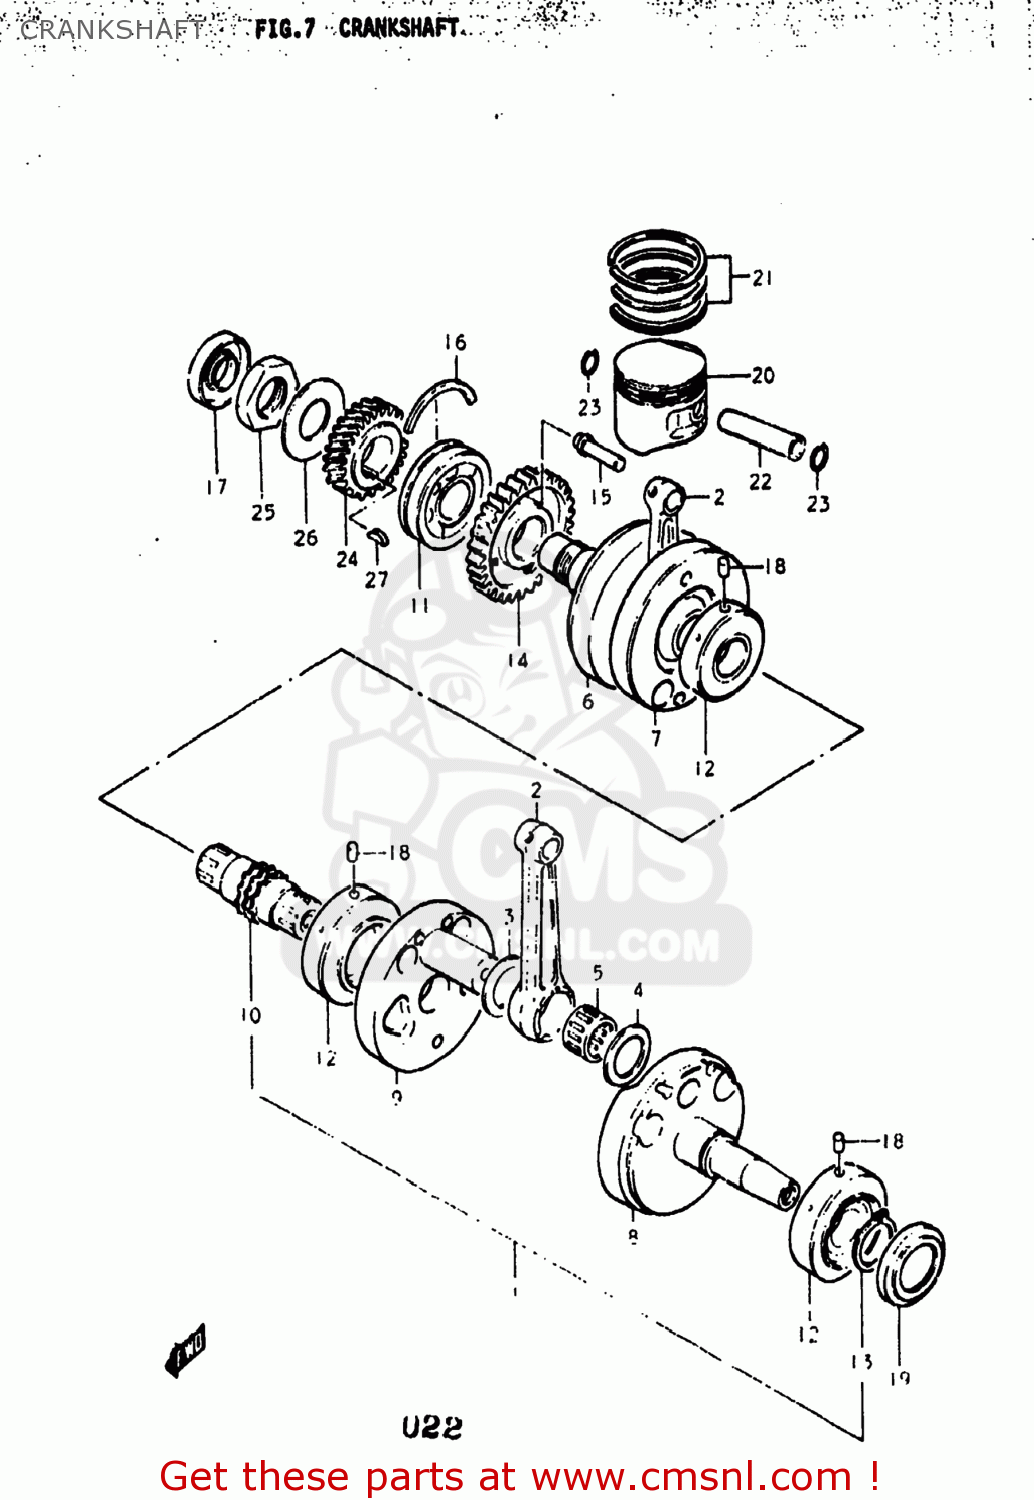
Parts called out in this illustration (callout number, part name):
1	CRANKSHAFT ASSEMBLY
2	CONNECTING ROD
3	WASHER (28X48X2)
4	WASHER(28X48X1)
5	BEARING(28X38X19.8)
6	CRANKSHAFT
7	WEB,CRANK
8	CRANKSHAFT,LEFT
9	WEB,CRANK
10	SHAFT,TIMING CHAIN DRIVE
11	BEARING(30X72X19)
12	BEARING
13	CIRCLIP.32MM
14	GEAR,CRANK BALANCER DRIVE
15	PIN
16	C RING
17	SEAL,OIL(25X47X8)
18	PIN
19	OIL SEAL
20	PISTON
21	RING SET,PISTON
22	PIN,PISTON
23	CIRCLIP
24	GEAR,PRIMARY DRIVE
25	NUT
26	WASHER
27	KEY
